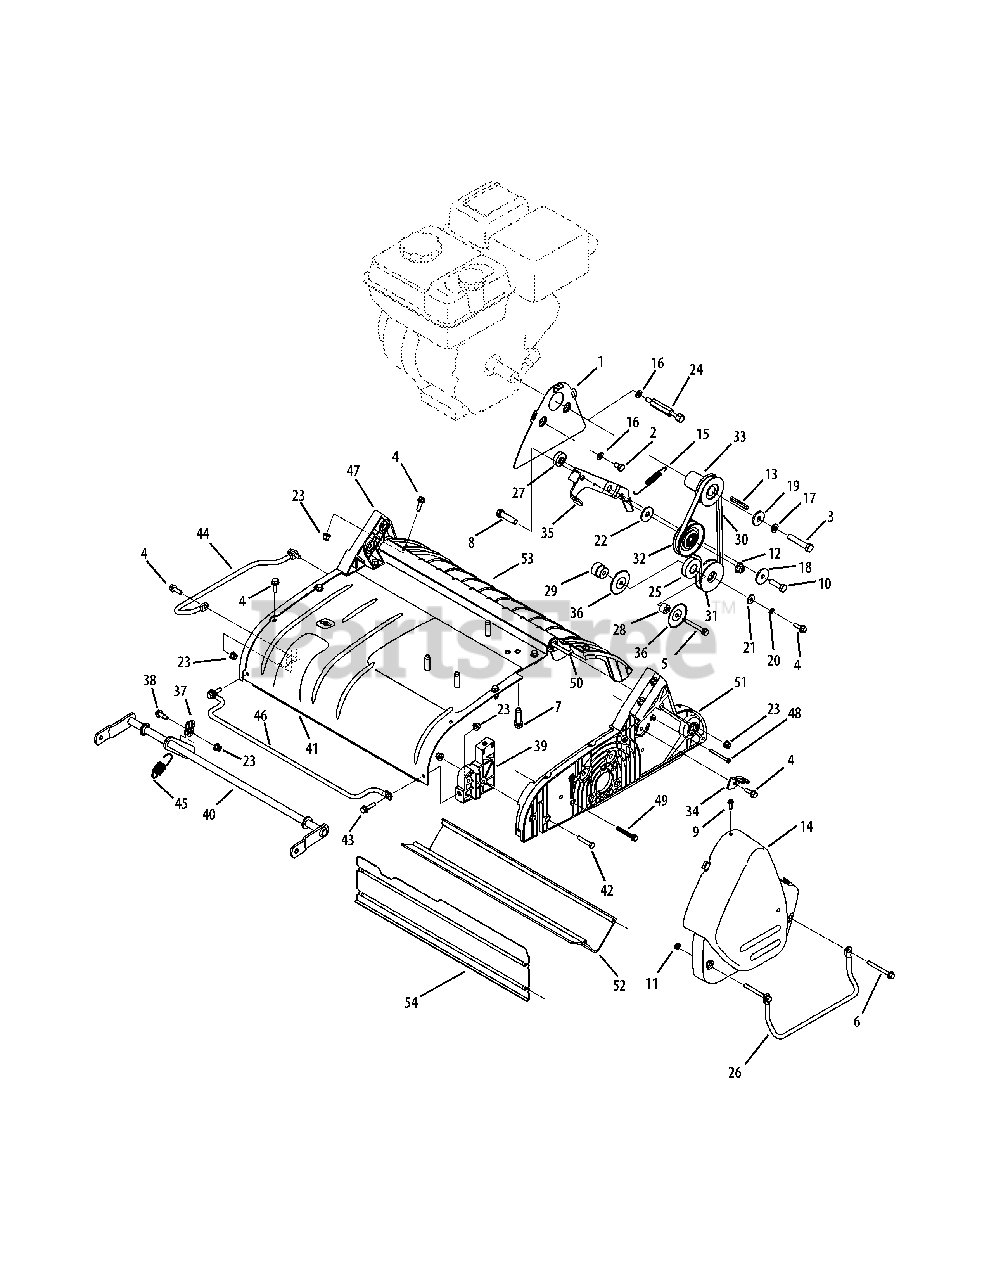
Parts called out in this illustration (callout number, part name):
1	Pulley Guard Assembly
2	Hex Screw, 5/16 - 24
3	Hex Screw, 3/8 - 24
4	Screw, M6 - 1 x 20.0
5	Screw, M6 - 1
6	Screw, M6 - 1
7	Sems Screw, 3/8 - 16
8	Hex Screw, 3/8 - 16
9	Screw, .625
10	Hex Screw, M8 - 1.25
11	Jam Nut, 1/4 - 20
12	Flange Lock Nut, 3/8 - 16
13	Square Key, 3/16 x 1.75
14	Pulley Cover
15	External Spring
16	Lock Washer, 5/16
17	Lock Washer, 3/8
18	Flat Washer, .330 x 1.25 x .120
19	Flat Washer, .395 x 1.12 x .14
20	Lock Washer
21	Flat Washer, 6.4 ID
22	Flat Washer, 10.5 ID
23	Flange Lock Nut
24	Belt Retainer Screw
25	Ball Bearing
26	Bumper Side
27	Idler Spacer
28	Bearing Spacer, 6.6 x 16.7 x 11.6
29	Idler Spacer, 6.5 x 22.3 x 23
30	V Belt
32	Pulley, 2 x 2.75 x .625
33	Pulley, .75 ID x 2.14
34	Cable Bracket Mount
35	Idler Arm
36	Washer Bearing
37	Cable Retainer Bracket
38	Shoulder Spacer, 7.13 x 11.50
39	Wheel Cradle Bracket Assembly
40	Height Adj. Bracket Assembly
42	Screw, M6-1 x 35.0
43	Screw, M6 - 1 x 25.0
44	Right Hand Bumper Side
45	Spring, 17.6mm x 54.0mm
46	Front Bumper
47	Right Hand Frame Assembly
48	Tap Screw
49	Screw, 1/4 - 20
50	Deflector Mounted Rod
51	Left Hand Frame Assembly
52	Rear Baffle
53	Deflector
